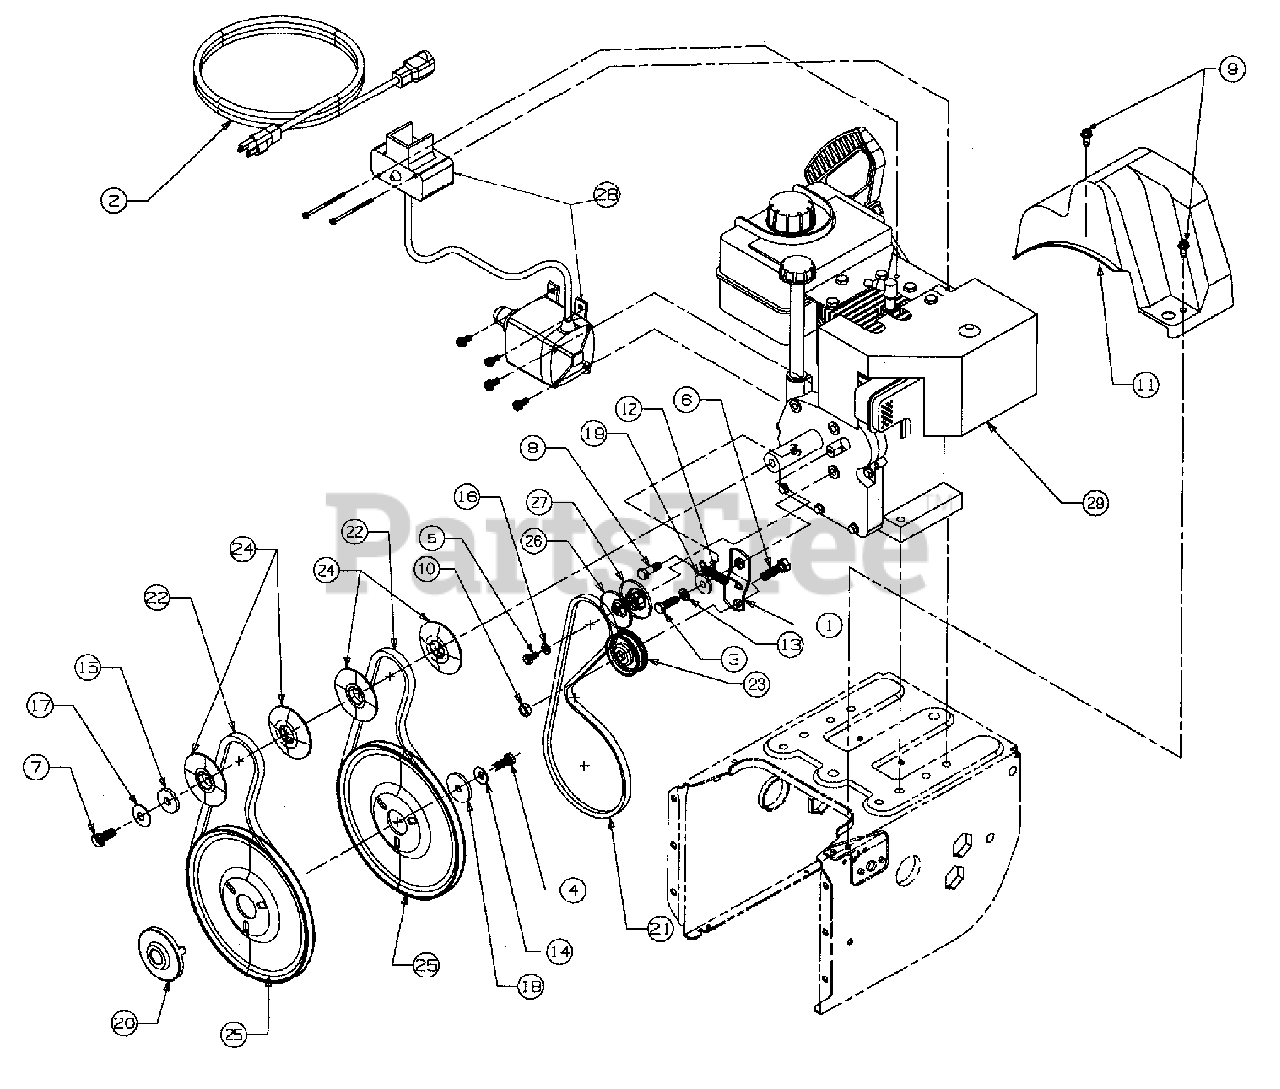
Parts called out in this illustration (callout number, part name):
3	Screw
4	Screw
5	Screw
6	Screw
7	Screw
8	Screw
9	Screw
10	Nut, Hex
11	Belt Cover
12	Spring
13	Washer-Flat
14	Washer-Bell
15	Washer-Flat
16	Washer-Lock
17	Washer-Bell
18	Washer-Flat
19	Shoulder Spacer
20	Pulley, Adapter
21	V-Belt
22	V-Belt Matched
23	Idler, Flat
24	Pulley, Half
25	Pulley-Auger
26	Pulley Half
27	Pulley Half
28	Starter
29	Engine
